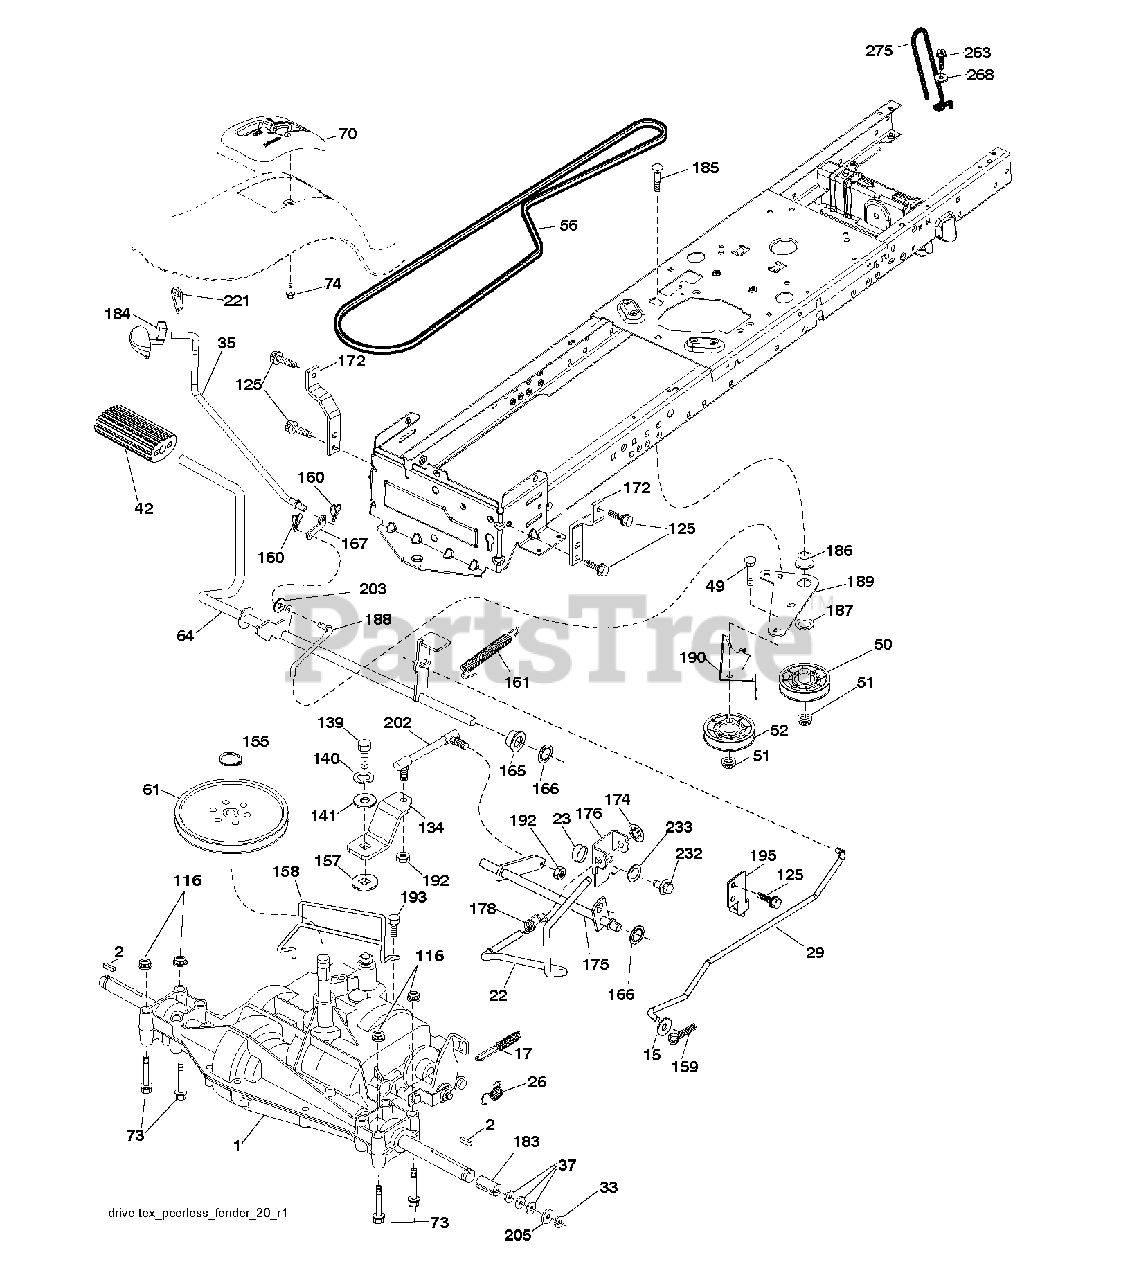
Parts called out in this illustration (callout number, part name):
2	SQUARE KEY
17	SPRING.BRAKE.PEERLESS.TEX
22	ROD.SHIFT.FENDER.TLT.2006
23	KNOB.DUCKHEAD.1/2
26	SPRING.BRAKE.RTN.GR.DR
29	ROD.BRAKE.PEERLESS
33	E-RING LT
35	ROD, BRAKE, PARK
42	PEDAL COVER T
49	BOLT
50	IDLER.FLAT.910.OFFSET
51	NUT LOCK FLG 3/8-16 UNC
52	IDLER.V-GROOVE.910.OFFSET
56	V-BELT.TRACTOR.DRIVE.P
61	PULLEY TRANS
64	SHAFT.ASM.PEDAL.BRAKE.
70	CONSOLE.SHIFT.
73	BOLT HEX 5/16-18 GR 5
74	SCREW.HI-LO.CONSOLE
116	NUT LOCK HEX FLANGE 5/16-18
125	SCREW
134	ARM SHIFT
139	BOLT 1/4-28X3/4
140	LOCKWASHER
141	WASHER LT
155	RETAINING RING LT
157	WASH-SHFT PLT LT
158	KEEPER.PMS.18/20.D4365
159	COTTER PIN
160	RETAINER CLIP
161	SPRING, RETURN LT
165	BUSHING.SHAFT.BRAKE.HAND
166	NUT.PUSH.625.2006
167	LATCH.BRAKE.SPRING
172	STRAP.TRQ.LH.GEAR.DRIV
174	NUT.PUSH.500.2006
175	SHAFT ASM SHIFT
176	ARM.CLEVIS.ROD.SHIFT
178	SPRING.SHIFT.GT2006
183	SPACER AXLE
184	HANDLE PARKING BRAKE
186	SPACER.RETAINER
187	WASHER 12/32X2X10GA
188	LINK.CLUTCH.GROUND.DRIVE
189	BELLCRANK.GROUND.DRIVE.TEX.
190	KEEPER.BELLCRANK.DRIVE
192	NUT LOCK CENTER 1/4 -28 FNTHD
193	SCREW 5/16"
195	BRKT.ROD.BRAKE.PEERLES
202	LINK.SHIFT.PMST.18"
203	WASHER
221	RETAINER.SPRING.CLIP.H
232	BOLT FIN HEX 7/16-14 X 1
233	WASHER SERRATED
263	SCREW, 3/8-16X3/4
268	WASHER
